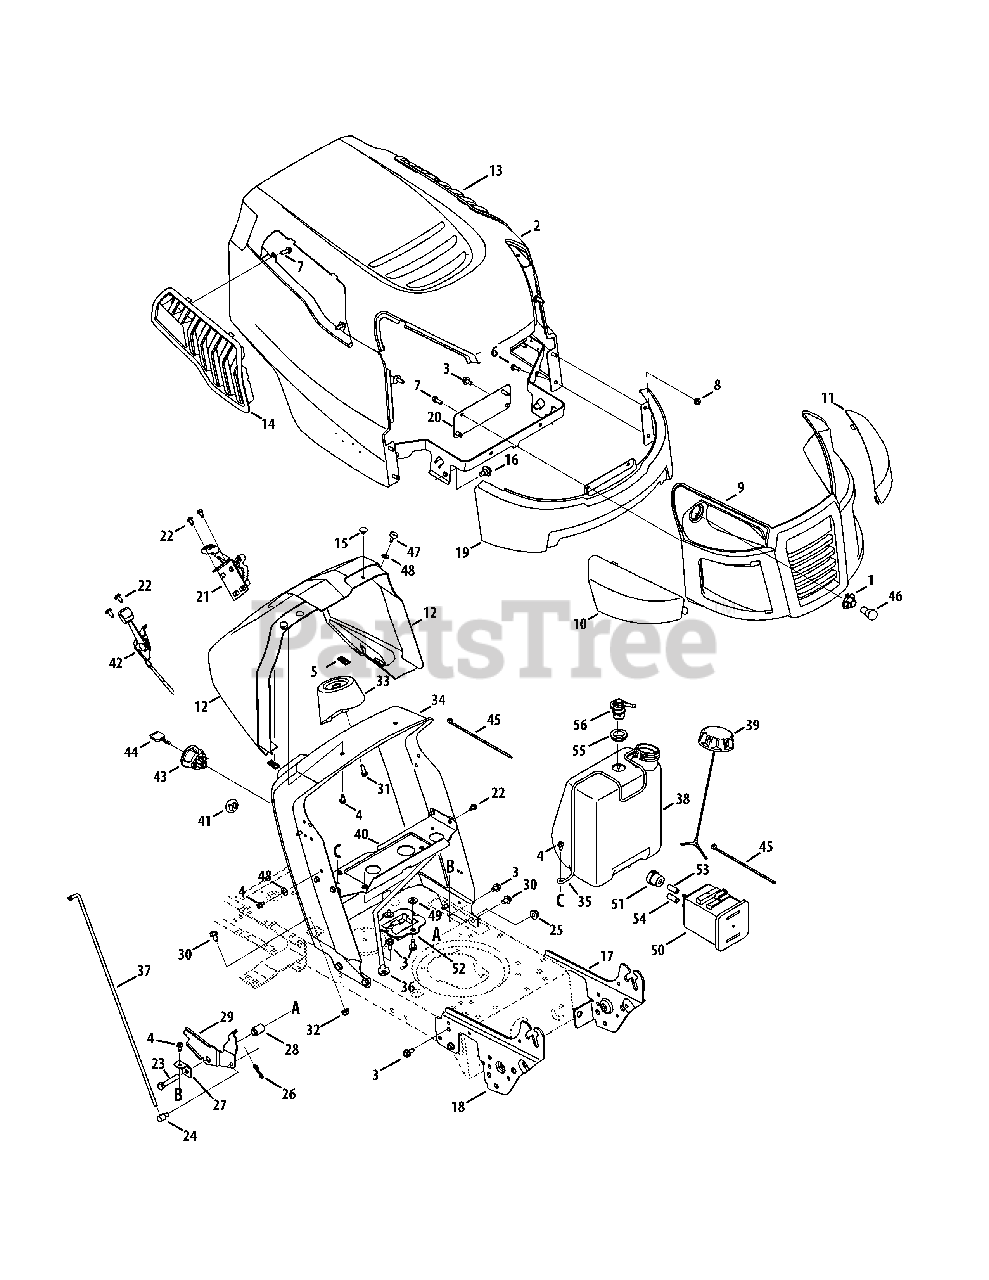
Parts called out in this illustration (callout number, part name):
1	Bulb Socket
2	Hood Assembly
3	Screw, 5/16-18 x .750
4	Hex Washer Screw, 1/4-20 x .500
5	Tin Clip Nut, 1/4-20
6	Hex Screw, 1/4-20 x .620
7	Screw, 1/4 x .750
8	Nut, Hex Flange Insert Lock, 1/4-20
10	Headlight Lens, RH
11	Headlight Lens, LH
12	Dash Collar
13	Hood Scoop, LH
14	Hood Scoop, RH
15	Bumper
16	Shoulder Screw, 5/16-18
17	Left Support Pivot Bracket
18	Right Support Pivot Bracket
19	Lower Grill
20	Lower Grill Bracket
21	Speed Selector, 7-Speed
22	Self-Tap Screw, 1/4-20
23	Hex Head Screw, 3/8-16
24	Ferrule, 1/4-20 x 1.00
25	Nut, Hex Flange Insert Lock, 3/8-16
26	Cotter Pin
27	Speed Latch Support Tab
28	Flange Spacer
29	Speed latch
30	Self-Tap Screw, 5/16-18
31	Hex Screw, 1/4 x .750
32	Nut, Hex Flange Lock, 5/16-18
33	Steering Support
35	Fuel Tank Support Rod
36	Dash support Rod
37	Speed Selector Control Rod
38	1.36 Gallon Fuel Tank
39	Fuel Cap
40	Gas Tank Support Bracket
41	Choke Plug
42	Throttle/Choke Assembly
43	Key Switch Module
44	Key (2 pack)
45	Cable Tie
46	Headlight Bulb
47	Ratchet Clip: .250 x .500
48	Flat Washer, .25 x .630 x .0515
49	Screw, Hx. Hd., 5/16-18 x .75
50	Carbon Canister
51	Canister Filter Vent
52	Canister Adapter Bracket
53	Low Perm Fuel Line 3/16 Wht.
54	Low Perm Fuel Line 7/32 Yel.
55	Rubber Grommet
